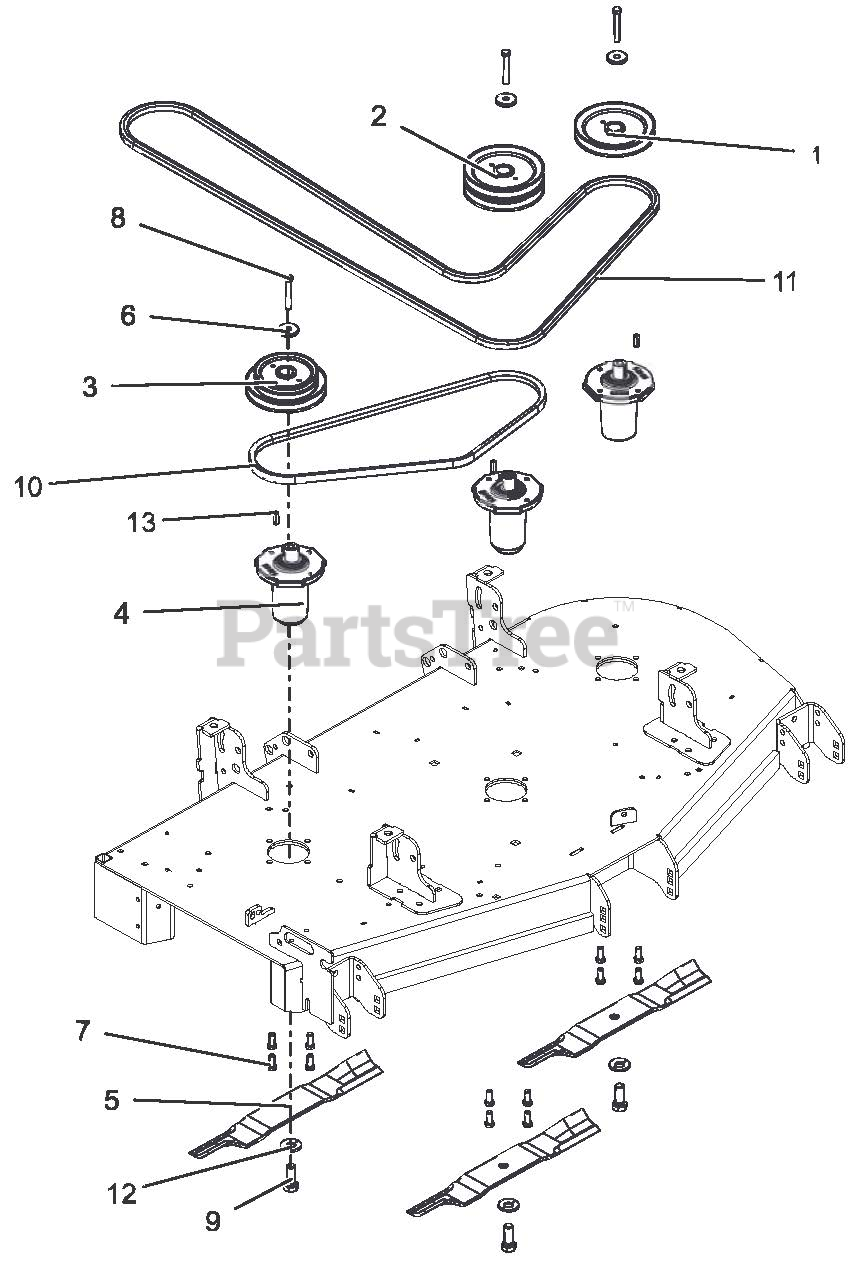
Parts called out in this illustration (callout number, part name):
1	PULLEY, SINGLE -1" ID X 6.00" OD-BLACK
2	PULLEY, DOUBLE -1" ID X 6.00" OD-BLACK
3	PULLEY, DOUBLE -1" ID X 6.00" & 4.75" OD
4	SERVICE, ASM SPINDLE- DUCTILE
5	BLADE, 18.00" MOVER
6	RETAINER, SHEAVE SPINDLE
7	BLT-HEX .38-16X1.00 GR5 YWZC EP30
8	BLT-HEX .38-16X2.75 GR8 YWZC
9	BLT, HEX .62-18X1.75 GR8 YWZC
10	BELT, B 56.00 RAW COGGED
11	BELT, BB 118.00 WRAPPED HEX
12	WSHR, BLVL .63X1.625X.14
13	KEY-SQ .250X.250X1.00 RC 40-50
